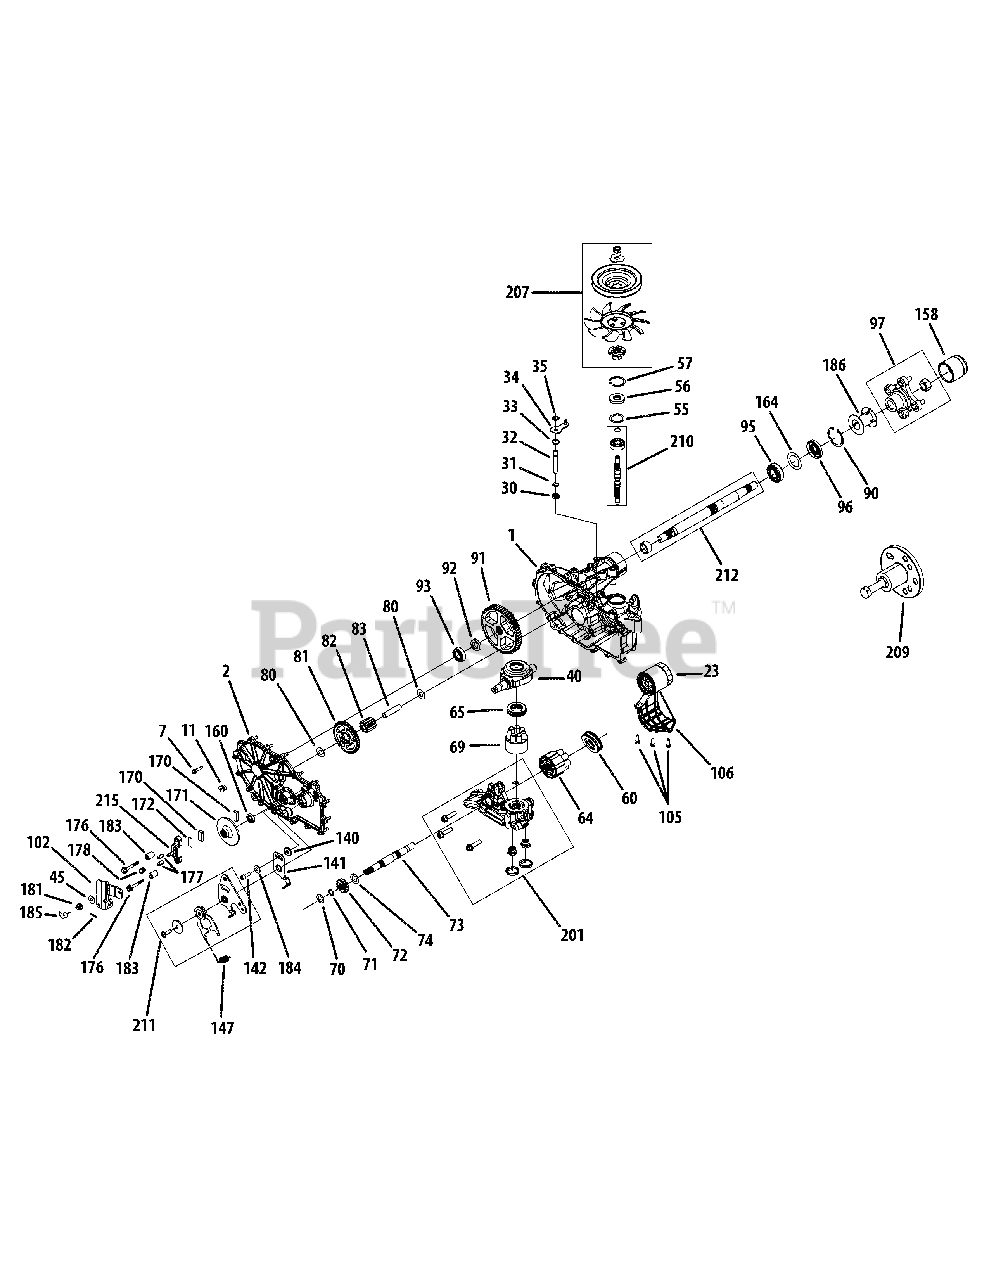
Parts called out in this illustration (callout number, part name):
1	Kit, Housing, Main, LH
2	Kit, Cover Side LH Control
7	Screw, Hex Washer
23	Filter, Spin-On 2.6 x 3.0
30	Seal, Lip, .375 x .75 x .25
31	Ring, Retaining .375 External
32	Rod, Bypass
33	Ring Retaining .750 Internal
34	Arm, Bypass
35	Ring, Ret .375 External
40	Trunnion, Swashplate
45	Washer, .34 x .88 x .06
55	Washer, 1.23 x 1.57 x .04
56	Seal, Lip 17 x 40 x 7
57	Ring Retaining Internal
60	Bearing, Thrust 35 x 62 x 18
64	Kit, 16cc Cylinder Block Assembly
65	Thrust Bearing, 30 x 52 x 13
69	Kit, Block, 7 Piston
70	Washer, .63 x 1.00 x .05
71	Ring, Reatining, Motor Shaft
72	Gear, 16T
73	Shaft, Motor
74	Washer, .71 x 1.16 x .04
81	Gear, 43T
82	Gear, 11T
83	Pin, Jackshaft
90	Ring, Retaining 2.25 Internal
91	Gear, 54T
92	Spacer, .750 x 1.00 x .257
93	Bearing, Ball 3/4 x 40mm x 12mm
95	Bearing, Ball 25.4 x 52 x 15
96	Seal, Lip, 1.0 x 2.06 x .38
97	Kit, Hub 4-Bolt
102	Arm, Brake
105	Screw, Hex Washer 1/4-20 x .75
106	Guard, Filter, LH
140	Spacer, .320 x 1.005 x .150
141	Arm, Neutral Right
142	Socket Cap Screw, 5/16-24 x 7/8
147	Spring, Extension
158	Cap, Axle
160	Seal, Lip .625 x 1.00 x .250
164	Spacer, 1.355 x 2.035 x .021
170	Puck, Brake
171	Rotor, Brake
172	Puck, Plate
176	Screw, .250-20 x 2.0 HFS Patch
177	Pin, Brake Actuating
178	Compression Spring
181	Nut, Castle 5/16-24
182	Pin, Cotter 3/32 x 3/4
184	Washer, .34 x .88 x .06
185	Spring, Brake Arm Bias
186	Tube, Axle 2.03
200	Kit. Seal, ZT-2800
201	Kit, Center Section RH
207	Kit, Fan Pulley
207	Fan Only
207	Pulley Hub
209	Kit, Hub Puller
210	Kit, Input Shaft
211	Kit, RTN Bidirectional
212	Kit, Shaft Axle
215	Kit, Brake Yoke
